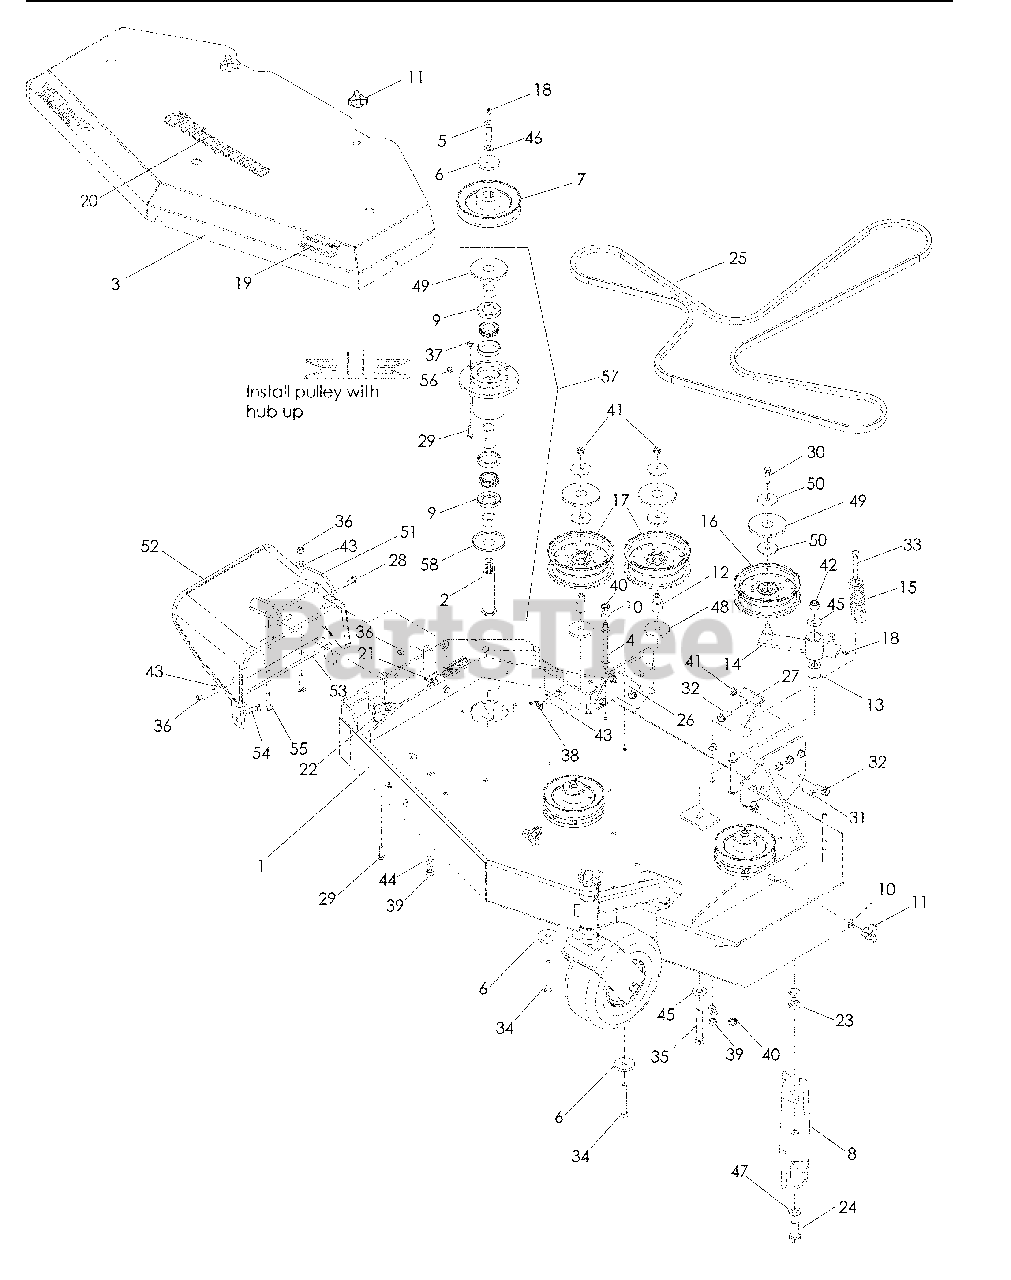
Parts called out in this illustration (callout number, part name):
1	DECK W/DECALS
3	BELT SHIELD, 48"
4	SHIELD SPACER
5	HCS 7/16-20 x 1½ GR8 SPEC
6	HEAVY WASHER
8	BLADE, 16¼"
9	SHAFT SEAL
10	WASHER 3/8" SEALING
11	KNOB, THREE PRONG
12	BUSHING, IDLER
13	BUSHING, PIVOT
16	PULLEY, IDLER
17	PULLEY, IDLER
18	ZERK
19	DECAL, WH4817
20	DECAL, HUSQ
21	DECAL, SEVERING
22	DECAL, CPSC
23	BLADE SPACER
24	HCS 5/8-18 x 1½ TPBLT
25	BELT, DECK
26	DECK SLIDE, RT
27	DECK SLIDE, LT
28	HCS 5/16-18 x 1¼
29	HCS 5/16-18 x 1
30	HCS 3/8-16 x 1¼
31	HCS 3/8-16 x 1
32	HCS 3/8-16 x 1 WHIZLK
33	HCS 3/8-16 x 2½
34	HCS 3/8-16 x 3
35	HCS ½-13 x 3¼
36	NUT 5/16-18 HEX NYLOC
37	NUT 5/16-18 HEX CTRLK
38	NUT 5/16-18 WING NYLON
39	NUT 3/8-16 HEX NYLOC
40	NUT 3/8-16 HEX WHIZLK
41	NUT, 3/8-16 HEX CNTRLK
42	NUT ½ HEX NYLOC
43	WASHER, 5/16 STD FLT
44	WASHER, 3/8 FLAT STD
45	WASHER, ½ STD FLT
46	WASHER 7/16 SLW
47	WASHER 5/8 SLW
48	WASHER 3/8 SPECIAL
49	TOP DUST CAP
50	WASHER, HEAVY
51	PIVOT BRACKET, DECK
52	CHUTE, RUBBER
53	BRACKET, CHUTE
54	RHSNB 5/16-18 x 1¼
55	RHSNB 5/16-18 x 1½
56	GREASE POPPET
57	SPINDLE ASSEM
58	BOTTOM DUST CAP
